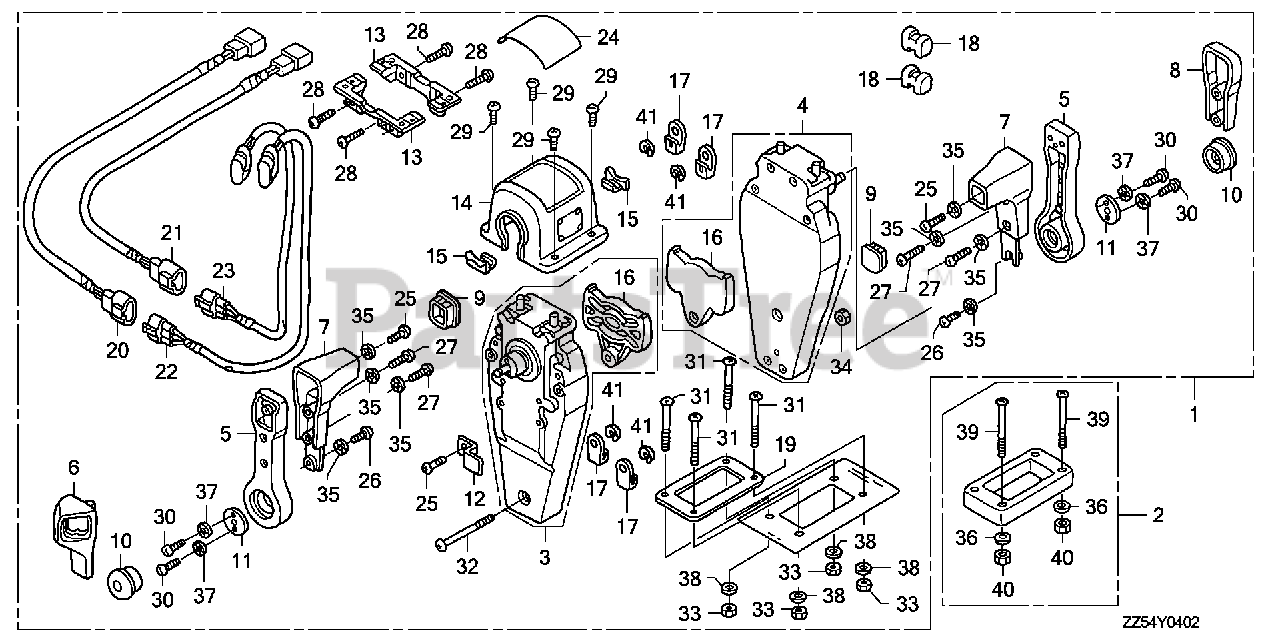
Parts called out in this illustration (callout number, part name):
1	BOX KIT, REMOTE CONTROL (TOP MOUNT DUAL)(R)
2	SPACER KIT, REMOTE CONTROL BOX (TOP MOUNT DUAL)
3	HOUSING ASSY., L. (INNER) (TOP MOUNT)
4	HOUSING ASSY., R. (INNER) (TOP MOUNT)
5	HANDLE, REMOTE CONTROL
6	COVER, L. GRIP
7	GRIP, REMOTE CONTROL HANDLE
8	COVER, DUAL GRIP
9	CAP, GRIP
10	BUTTON, THROTTLE
11	PLATE, HANDLE
12	PLATE, CABLE CLAMP
13	BRACKET, REMOTE CONTROL HOUSING
14	HOUSING, DUAL REMOTE CONTROL BOX
15	HOUSING, LEAD
16	PLATE, DWELL
17	TERMINAL, CABLE
18	SPACER, CABLE CLAMP
19	GASKET, DUAL
20	SUB-HARNESS ASSY., POWER TRIM-TILT (A)
21	SUB-HARNESS ASSY., POWER TRIM-TILT (B)
22	SWITCH ASSY., POWER TRIM-TILT (A)
23	SWITCH ASSY., POWER TRIM-TILT (B)
24	MARK, REMOTE CONTROL (DUAL)
25	SCREW, PAN (5X16)
26	SCREW, PAN (5X10)
27	SCREW, PAN (5X20)
28	SCREW, PAN (5X18)
29	SCREW, PAN (4X10)
30	SCREW, PAN (6X18)
31	SCREW, PAN (5X40)
32	SCREW, PAN (5X55)
33	NUT, HEX. (5MM)
34	NUT, HEX. (5MM)
35	WASHER, LOCK (5MM)
36	WASHER, PLAIN (5MM)
37	WASHER, LOCK (6MM)
38	WASHER, PLAIN (5MM)
39	SCREW, PAN (5X65)
40	NUT, HEX. (5MM)
41	E-RING (6MM)
